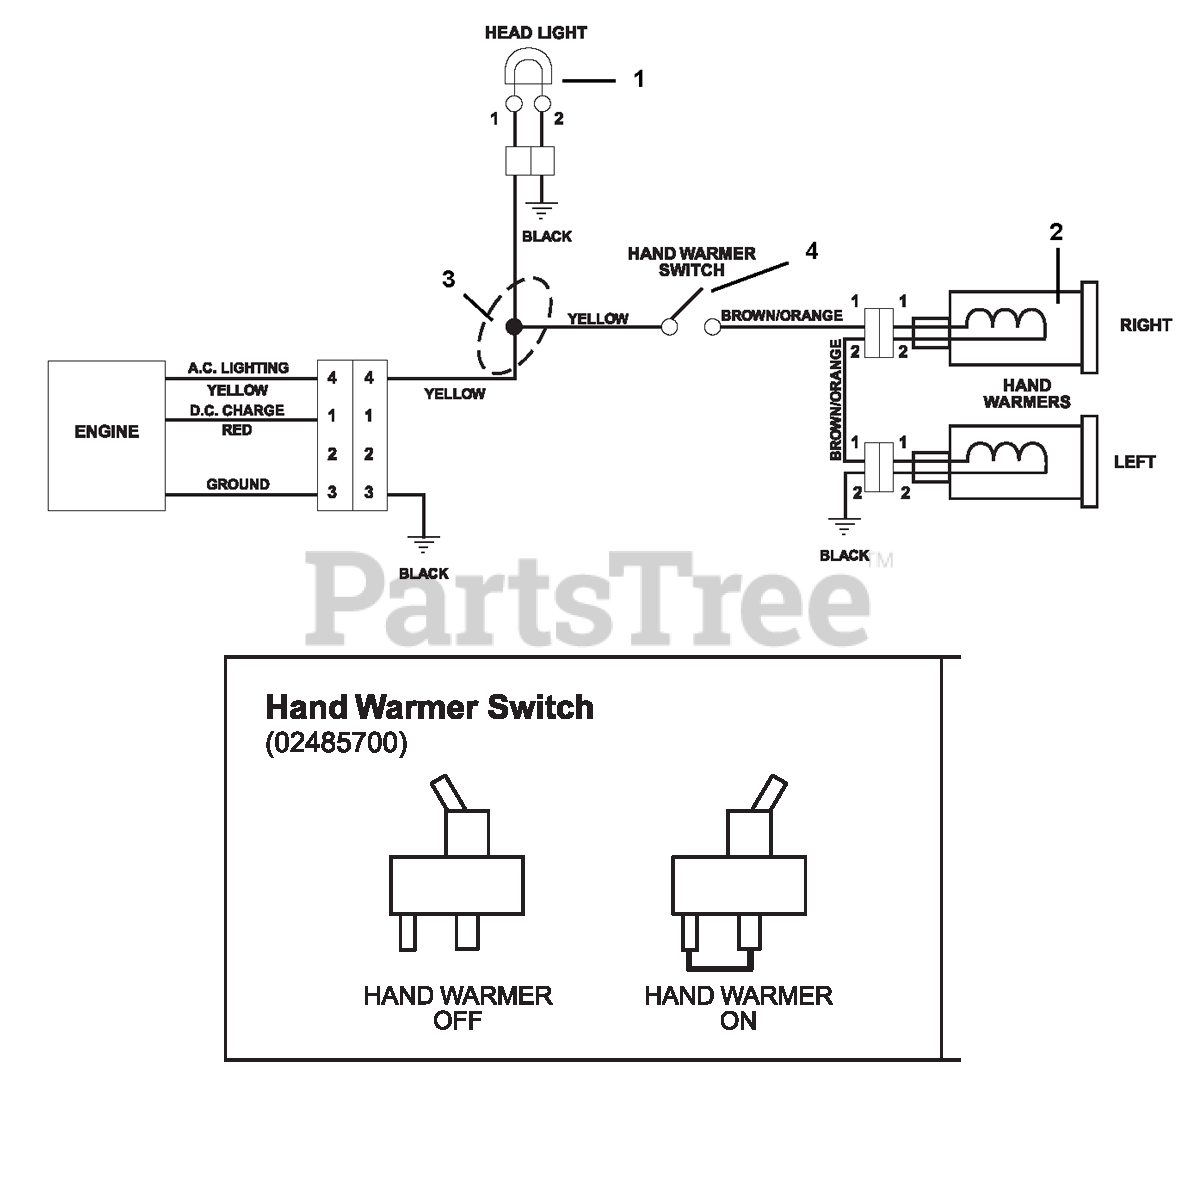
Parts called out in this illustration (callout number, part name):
1	LIGHT, HALOGEN ASSY.
2	HEATED GRIP, MAGURA
3	HARNESS, WIRE-LIGHT HANDWARMER
4	SWITCH, ON/OFF
